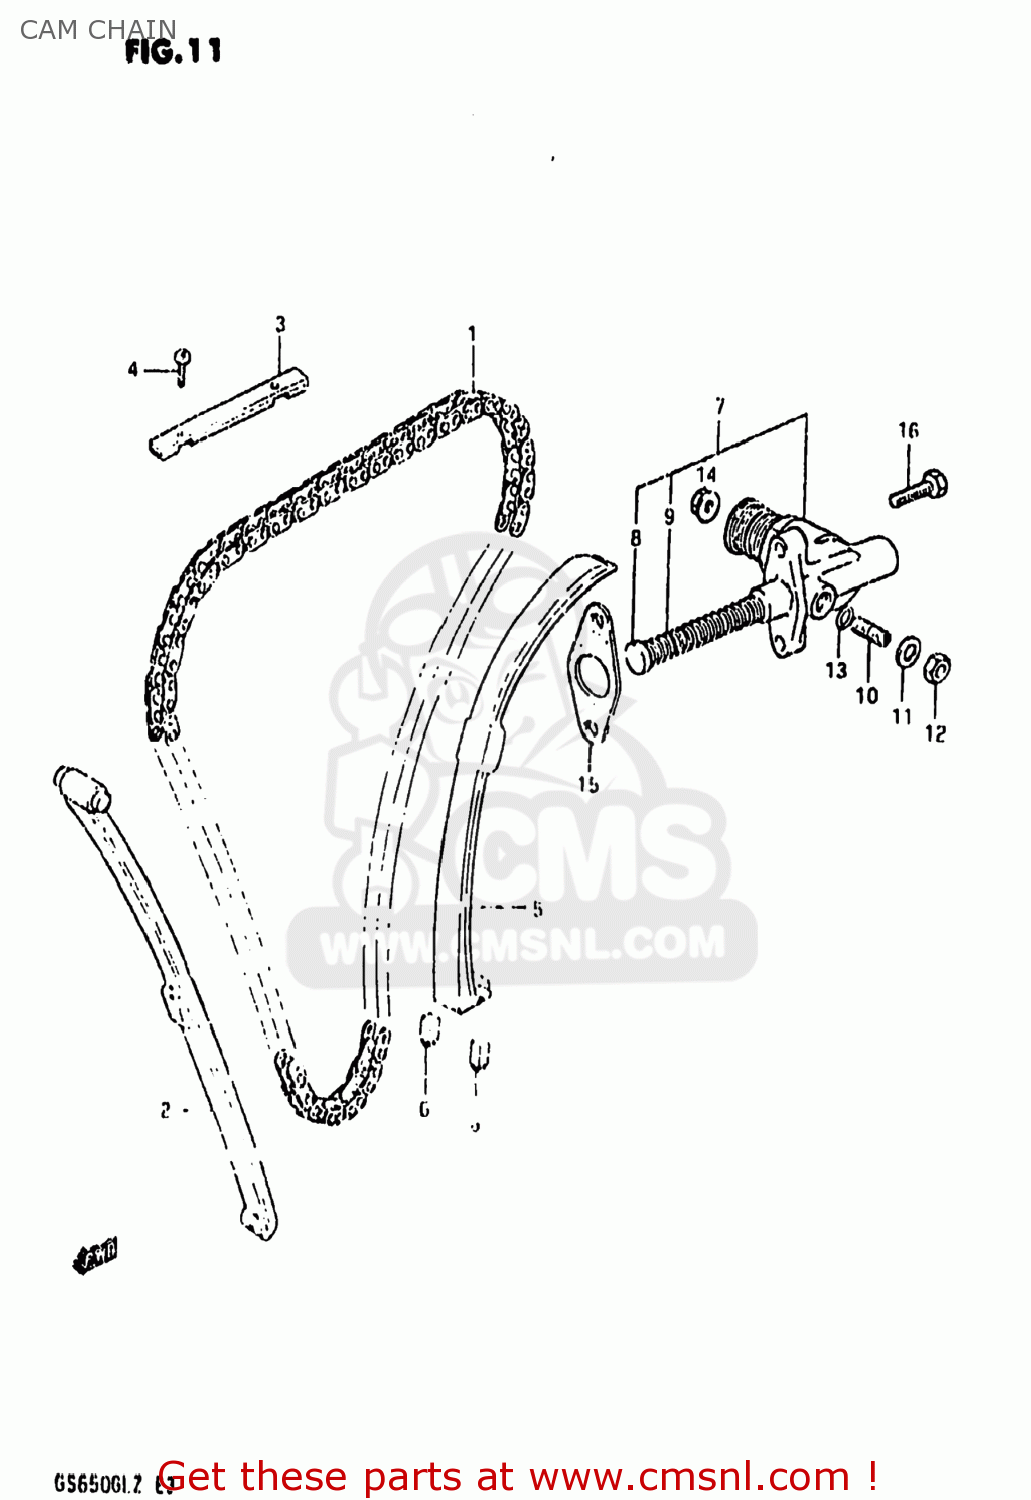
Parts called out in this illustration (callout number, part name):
1	CHAIN,CAMSHAFT DRIVE(120L)
2	GUIDE,CAM CHAIN
3	GUIDE,CAM CHAIN
4	SCREW
5	TENSIONER,CAM CHAIN
6	CUSHION,CAM CHAIN TENSIONER
7	ADJUSTER ASSEMBLY,TENSIONER
8	ROD,PUSH
9	SPRING
10	SCREW
11	WASHER
12	NUT
13	O-RING
14	NUT
15	GASKET,TENSIONER ADJUSTER (MCA)
16	SCREW (6X25)
